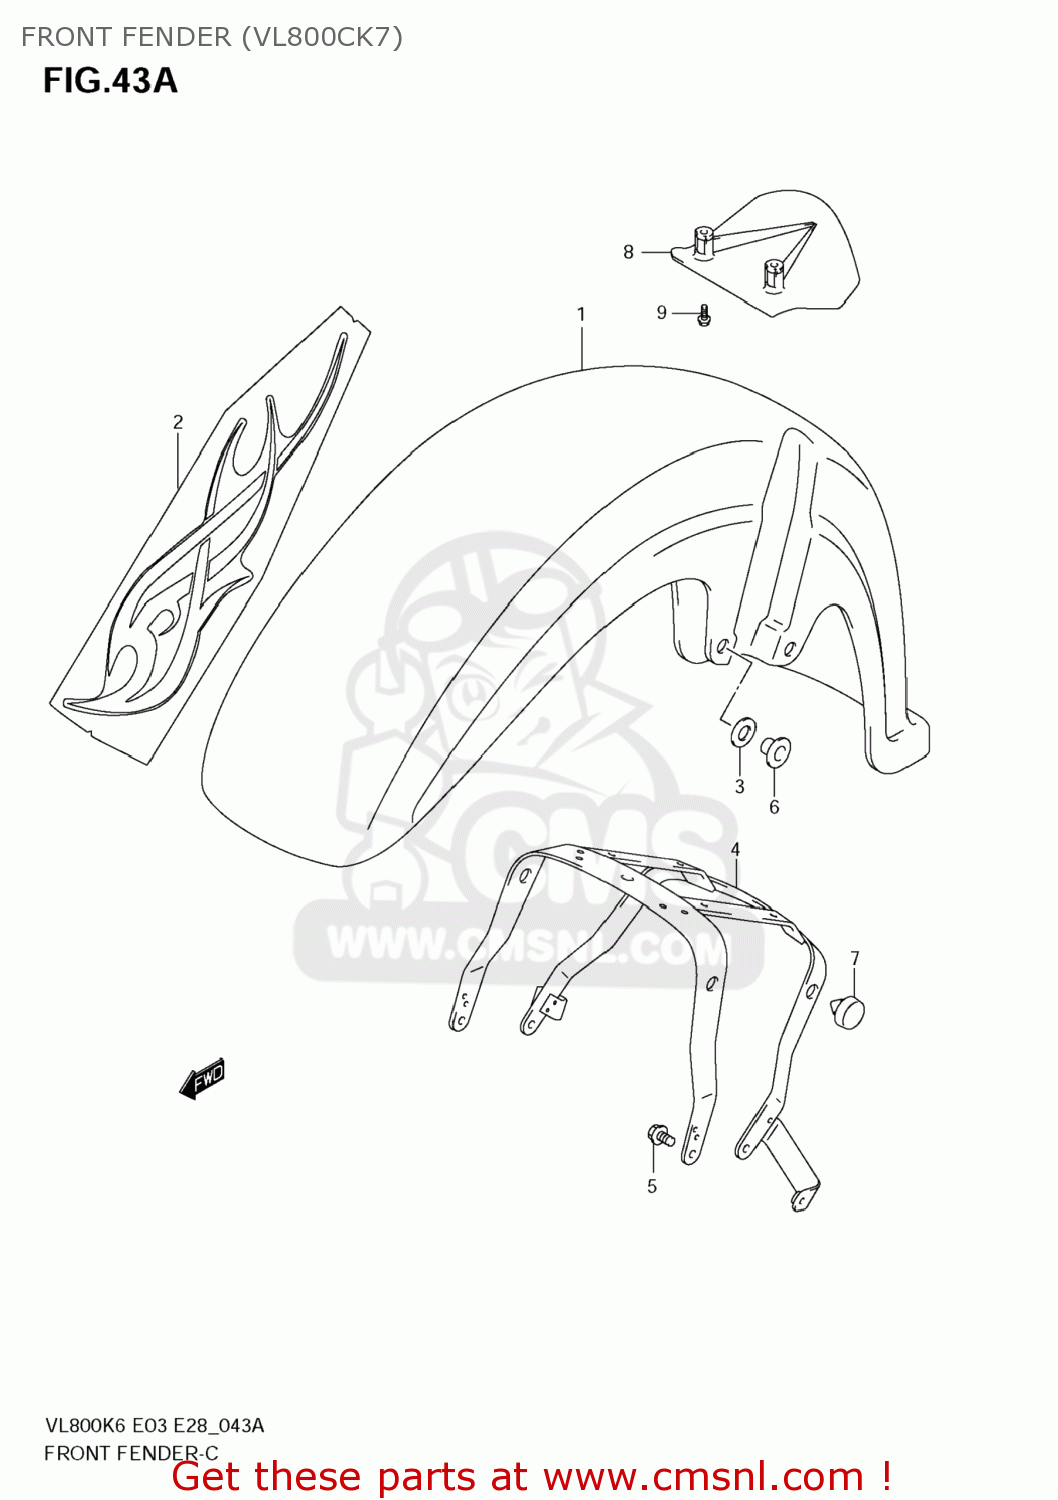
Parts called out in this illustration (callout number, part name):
1	FENDER,FR
2	TAPE,FR FENDER
3	CUSHION,FR FENDER
4	BRACE,FR FENDER
5	BOLT
6	WASHER,FR FENDER
7	CUSHION
8	WING,FR
9	BOLT(6X16)
